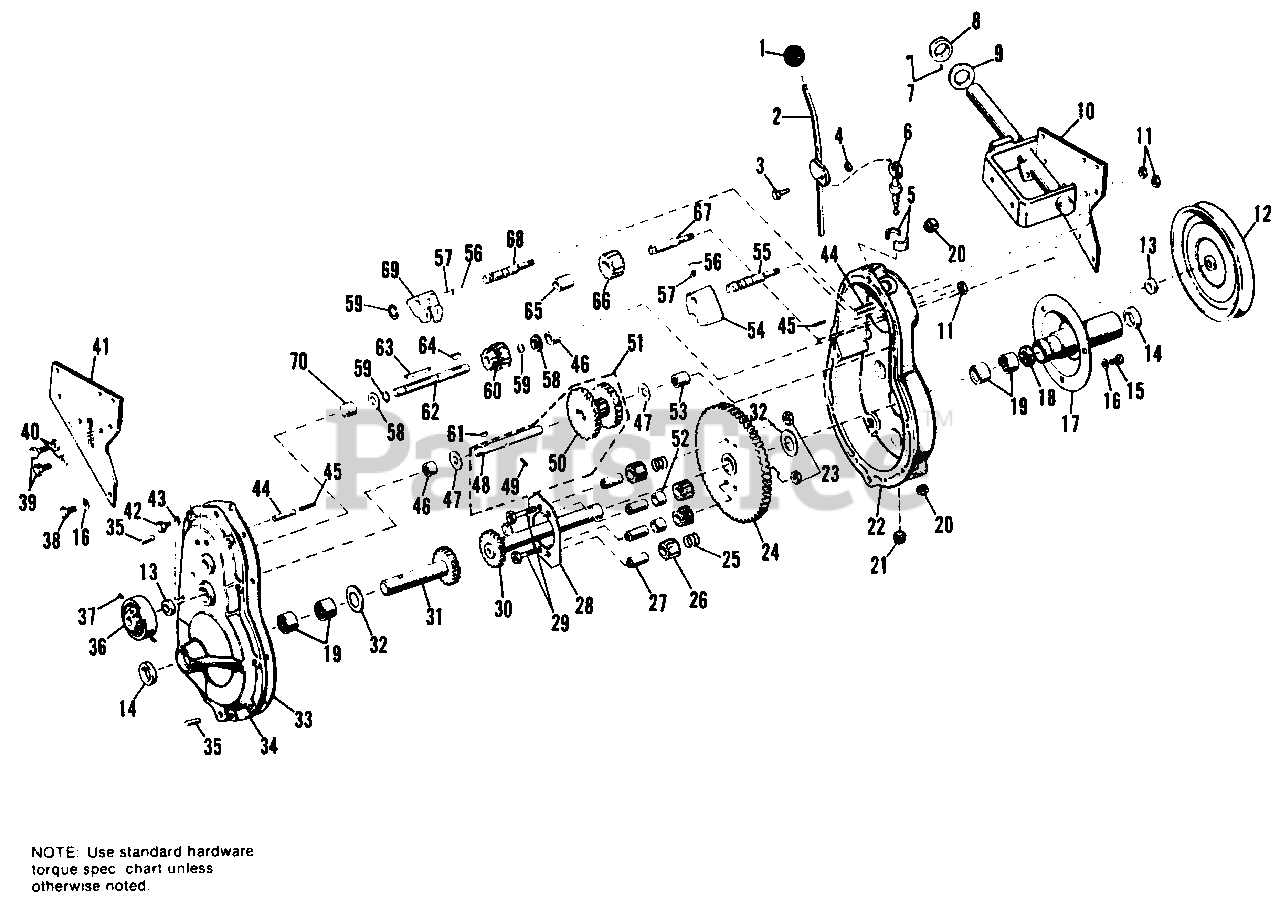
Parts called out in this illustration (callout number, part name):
2	LEVER ASSY., Shift
3	CAPSCREW, Hex Hd., 1/4-20 x 3/4
4	LOCKNUT, Hex, 1/4-20
5	BUSHING, Half
6	ROD ASSY., Shift
7	SETSCREW, 5/16-18 x 1/2
8	COLLAR, Set
10	PLATE ASSY., Side
11	NUT, Hex, Full, 7/16-14
12	PULLEY, Transmission
15	CAPSCREW, Hex Hd., 3/8-16 x 7/8
16	LOCKWASHER, 3/8
17	HOUSING ASSY., Axle
19	BEARING, Roller
21	PLUG, Pipe, 3/8
22	CASE ASSY., Gear
23	LOCKNUT, Hex, 3/8-16
24	GEAR ASSY., Drive
26	PINION, Diff.
27	SPINDLE, Diff.
28	PLATE, Diff.
29	CAPSCREW, Hex Hd., 3/8-16 x 2-1/2
30	SHAFT ASSY., Axle, R.H.
31	SHAFT ASSY., Axle, L.H.
34	COVER ASSY., Gear Case
35	PIN, Roll, 3/8 x 1
36	DRUM, Brake
37	SETSCREW, 5/16-18 x 5/16
38	CAPSCREW, Hex Hd., 3/8-16 x 3/4
39	CAPSCREW, Hex Hd., 7/16-14 x 3/4
40	LOCKWASHER, 7/16
41	PLATE, Side, Transmission
42	CAPSCREW, Hex Hd., 5/16-18 x 1-1/4
43	LOCKWASHER, 5/16
44	PIN ASSY., Roll
45	PIN, Roll, 3/16 x 1
46	BEARING, Roller
48	SHAFT, Brake
49	PIN, Dowel
50	GEAR ASSY., Cluster
51	GEAR ASSY., Cluster
52	SPACER, Diff.
53	BEARING, Roller
54	FORK, I & II
55	SHAFT, Hi-Lo
56	BALL, Shift Lock
59	RING, Retaining
60	PINION ASSY., Hi & Lo
61	KEY, Hi-Pro
62	SHAFT, Pulley
64	KEY, Hi-Pro
65	BEARING, Roller
66	PINION, Reverse
67	SHAFT, Reverse Pinion
68	SHAFT, Reverse
69	FORK, Shift, Reverse
70	BEARING, Roller
